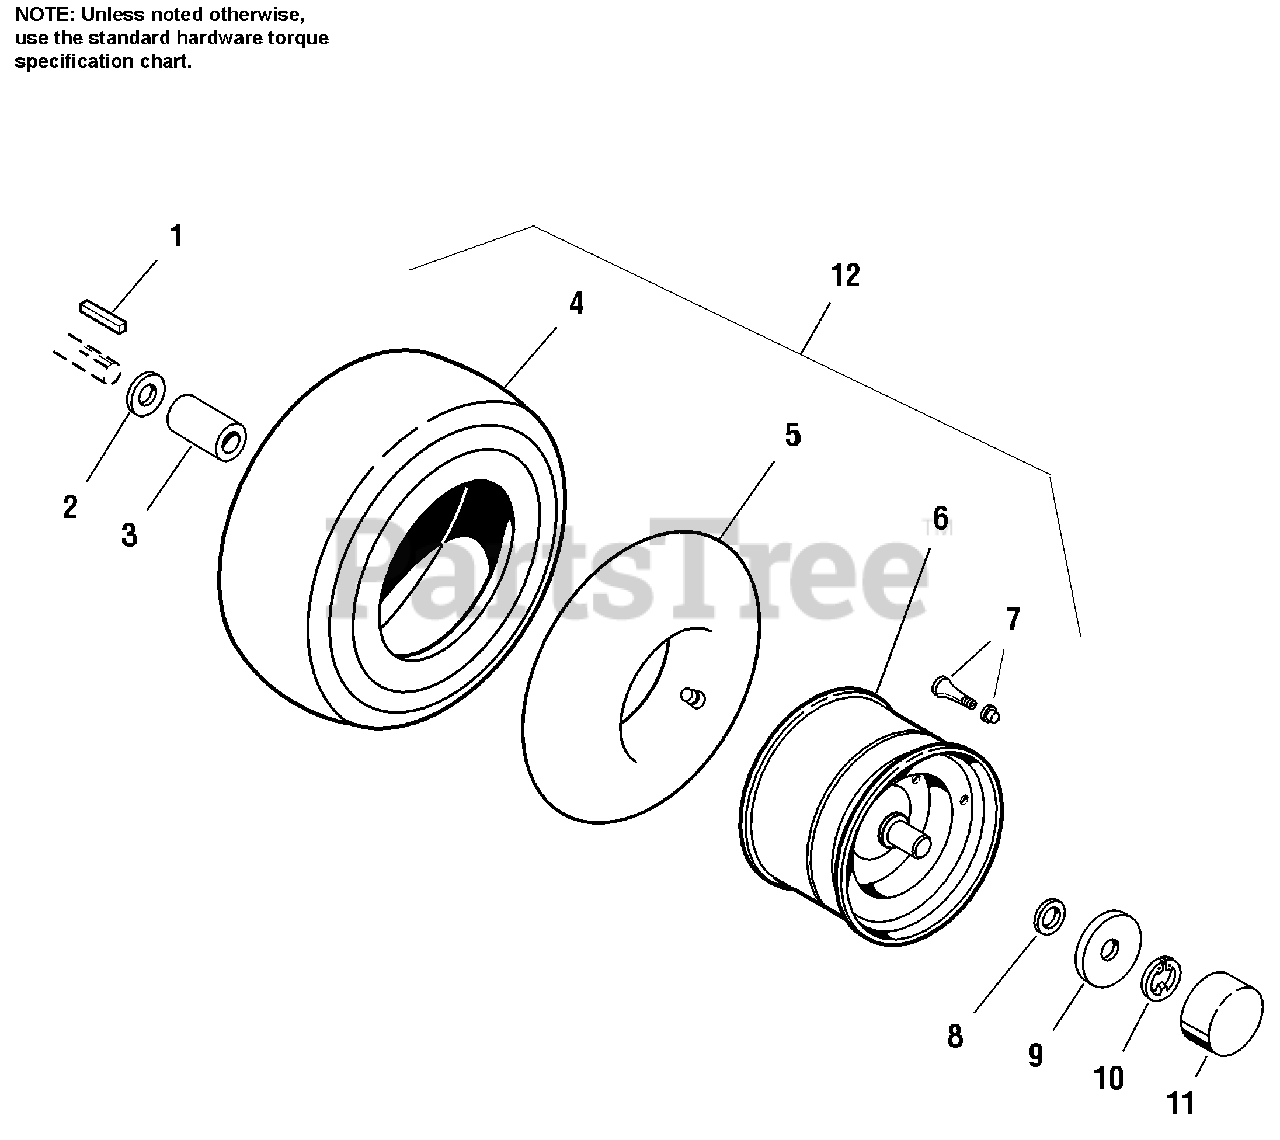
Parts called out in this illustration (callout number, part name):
4	TIRE, 20 x 8.00-8
5	TUBE
6	WHEEL ASSY., 20 x 8.00-8
7	VALVE STEM & CAP
8	WASHER
9	RETAINER, Cap, Hub
10	RING, Retainer
12	WHEEL & TIRE ASSY., 20 x 8.00-8
